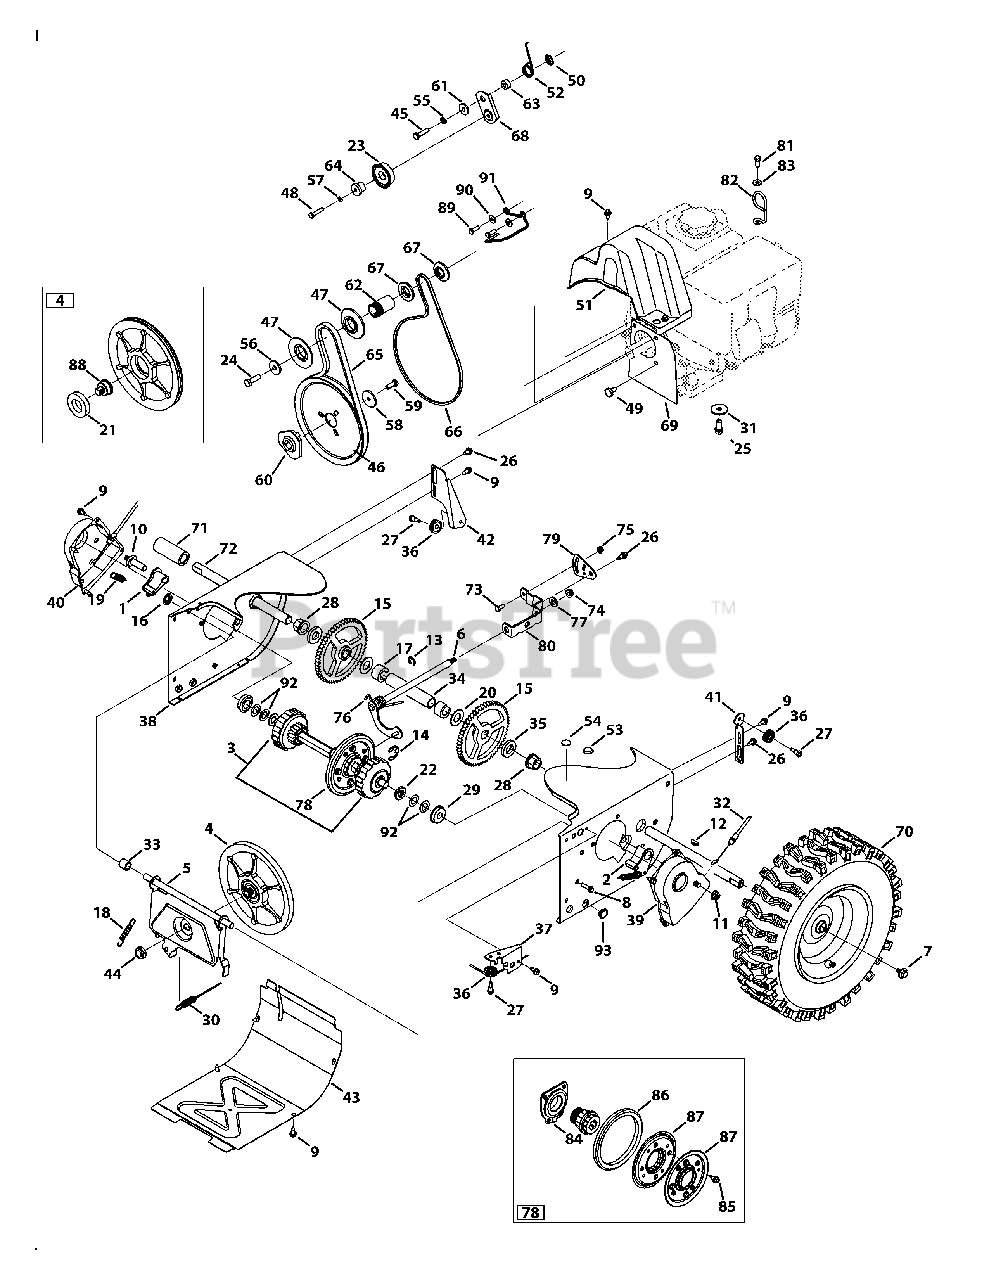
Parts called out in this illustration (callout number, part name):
1	Dogg Assembly, RH
2	Dogg Assembly, LH
3	Drive Shaft Assembly
4	Friction Wheel Disc Assembly
5	Friction Wheel Support Bracket
6	Rod Shift Assembly
7	Screw, 5/16-24 x .750
8	Screw, 1/4-20 x 1.000
9	Screw, 1/4-20 x .625
10	Actuator Shaft
11	Nut, Flangelock, 3/8-16
12	Hi-Pro Key, 3/16 x 3/4 DIA
14	Retainer Ring
16	Nut, Speed, .500
17	Spacer, .76 x .75
18	Extension Spring, .380 x 2.500
19	Extension Spring, .500 x 1.71
20	Washer, Flat, .76 x 1.49
21	Ball Bearing, 30 x 55 x 13
22	Spacer, .68 ID x 1.25 OD x .20
23	Idler Pulley Assembly
24	Hex Head Screw, 3/8-24 x 1.25
25	Taptite Sems Screw, 3/8-16 x 1.000
26	Screw, Shoulder, .368 x .113 x 1/4-20
27	Screw, Shoulder, .340 x .335 x 1/4-28
28	Hex Flange Bearing, .75 ID
29	Ball Bearing, 17 x 40 x 12
30	Drive Clutch Cable
31	Washer, Flat, .38 x 1.38
32	Steering Cable
33	Spacer, .508 x .75
34	Axle Support Tube
35	Spacer, Axle
36	Cable Roller
37	Auger Cable Guide Bracket
38	Wheel Drive Frame (24" & 28")
39	Shaft Retainer, LH
40	Shaft Retainer, RH
41	Auger Clutch Cable Guide Bracket
42	Drive Clutch Cable Guide Bracket
44	Nut, Flange, 5/8-18
45	Hex Head Screw, 5/16-24 x 1.25
46	Auger Pulley, 8.1 x .5
47	Pulley, Half, 2.600
48	Taptite Screw, 1/4-20 x 1.250
49	Shoulder Screw, .500 x .145
50	Nut, Push-On, .25 Dia.
51	Belt Cover
52	Spring, Torsion, .850 x .333
53	Plug, 3/8 ID
54	Plug, 1/2 ID
55	Washer, Lock, 5/16
56	Washer, Flat, .45 x 1.5
57	Washer, Lock, 1/4
58	Washer, Flat, .34 x 1.50
59	Hex Head Screw, 5/16-24 x .875
60	Pulley Adapter, .75 DIA
61	Spacer, Shoulder, .3175 x .500
62	Spacer, .875 x 1.185
63	Spacer, .340 x .750
64	Spacer, Shoulder, .260 x .785
65	Belt, .500 x 37
66	Belt, 3/8 x 35.68
67	Pulley, Half, 3/8 x 1.7160
68	Drive Idler Bracket
69	Cover Plate
70	Wheel, LH (24")
70	Wheel, RH (24")
71	Spacer, 1.25 x .75 x 3.00
72	Axle, .75 x 11.12
73	Hex Head Screw, 1/4-20 x .620
74	Nut, Flange Lock, 5/16-18
75	Nut, Flange Lock, 1/4-20
76	Spring, Torsion, .750 x .968
77	Washer, Flat, .469 x .875 x .105
78	Friction Wheel Assembly
79	Speed Selector Pivot Bracket
80	Speed Selector Shift Bracket
81	Hex Head Screw, 1.25 x 20
82	Cable Guide
83	Washer, Flat, .330 x .630
84	Bearing Assembly, Friction Wheel
85	Screw, 5/16-18 x .75
86	Friction Wheel, 5.5 OD
87	Friction Wheel Plate
88	Friction Pin, Disc Bearing
89	Hex Head Screw, 5/16-24 x 1.00
90	Washer, Flat, .349 x .879
91	Belt Guide
92	Flat Washer, .67 x 1.174 x .02
93	Plug, 5/8 Hole
